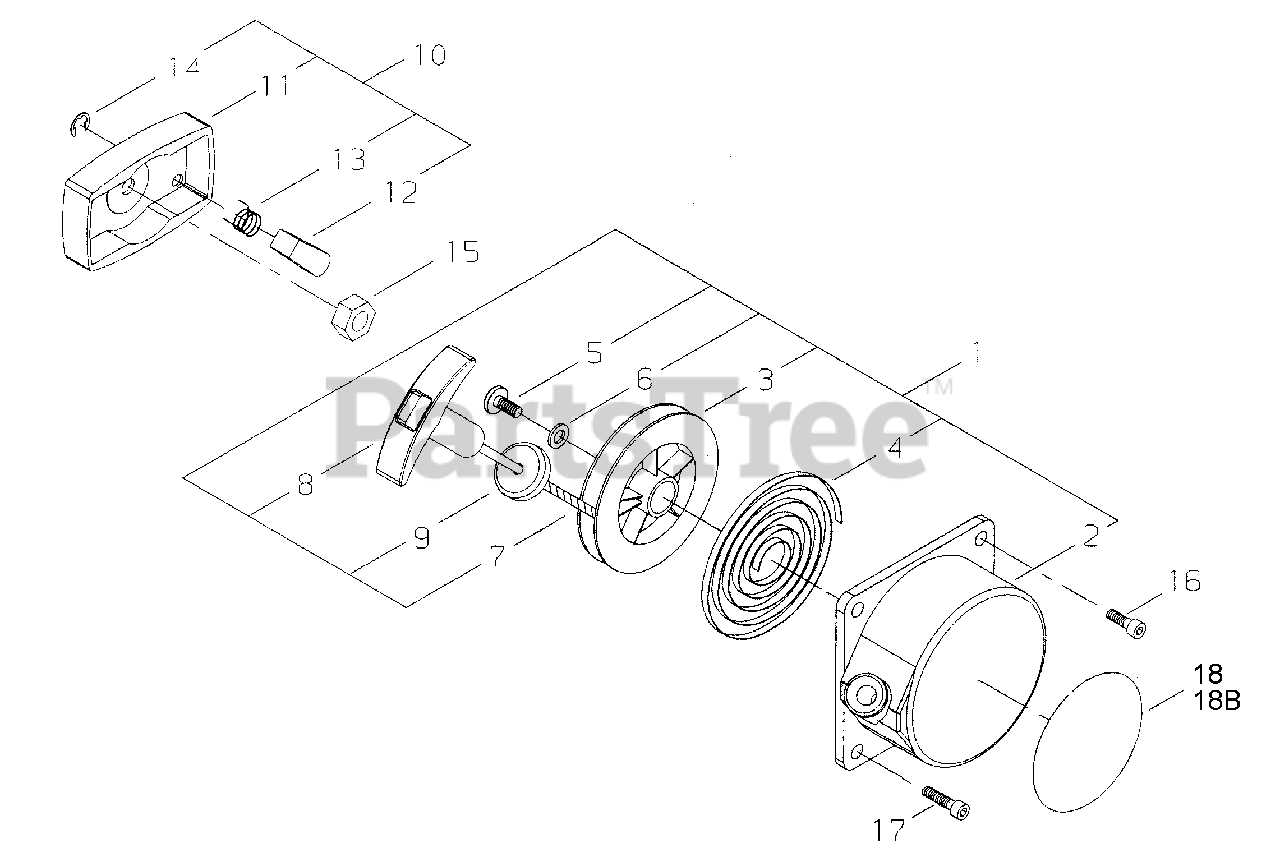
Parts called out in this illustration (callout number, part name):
1	STARTER ASSY, RECOIL
2	CASE, RECOIL STARTER
3	REEL, ROPE
4	SPRING, RECOIL
5	SCREW 5
6	WASHER
7	ROPE, STARTER
8	GRIP, STARTER
9	DAMPER
10	PULLEY ASSY, STARTER
11	PULLEY, STARTER
12	PAWL, STARTER
13	SPRING, RETURN
14	E-RING 4
15	NUT
16	BOLT M5×20
17	BOLT M5×25
18	LABEL, TRADE (RED)
18B	LABEL, TRADE (BLUE)
